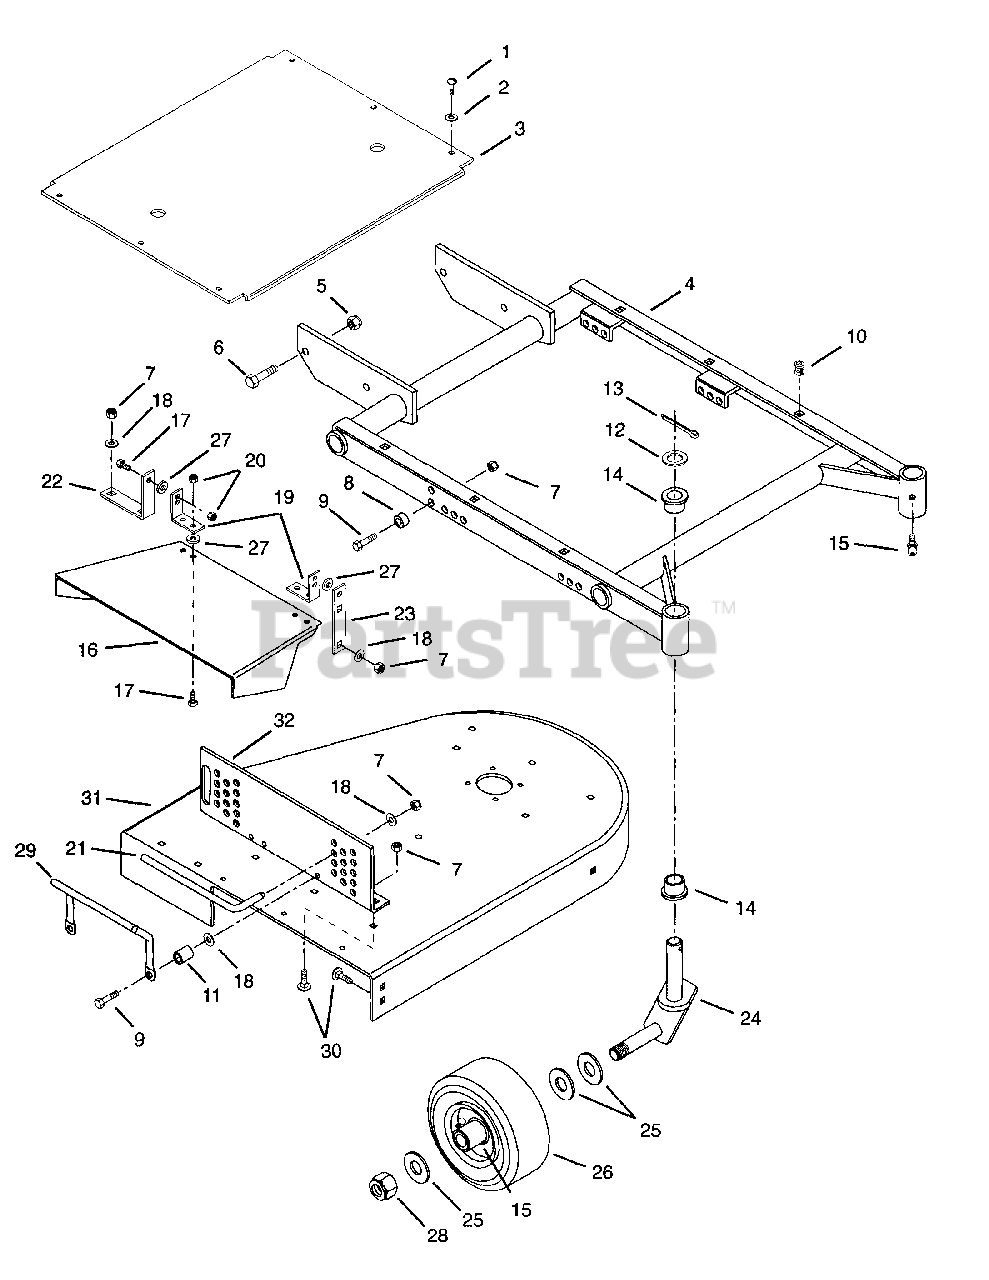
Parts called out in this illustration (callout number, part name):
1	Screw-Tapping .25-20 x .50 Hex Washer Head
2	Washer-Flat-Steel .281 x .625 x .065
3	Cover, Belt Pro Mower
4	Weldment-Mower Frame 36"
5	Nut-Locking-Center .61-11
6	Bolt-Hex .62-11 x 1.50
7	Nut-Locking-Nylon .38-16
8	Bushing .391 x .626 x .670
9	Bolt-Hex .38-16 x 1.50 Grade 5
10	Grommet, Plastic
11	Bushing
12	Washer-Hardened-Thrust 1.002 x 1.552 x .030
13	Pin-Cotter .188 x 1.50
14	Bushing-Flange 1.020 x 1.385 x .75 x 1.75
15	Fitting-Lube .25-28 x .256
16	Chute-Discharge
17	Bolt-Hex .31-18 x .75 Grade 5
18	Washer-Flat-Steel .406 x .812 x .065
19	Bracket, Discharge Chute
20	Nut-Locking-Nylon .31-18
21	Pin-Mower Locking
22	Bracket
23	Bracket
24	Weldment-Caster Fork
25	Washer-Flat-Steel .812 x 1.469 x .134
26	Wheel 9 x 3.50
27	Washer-Flat-Rubber .375 x 1.50 x .060
28	Nut-Locking-Nylon .75-10
29	Handle
30	Bolt-Round Head Square Neck .38-16 x 1.00 Grade 5
31	Weldment-36 inch Deck
32	Bracket-Mower Side Support - Left Hand
32	Bracket-Mower Side Support - Right Hand
